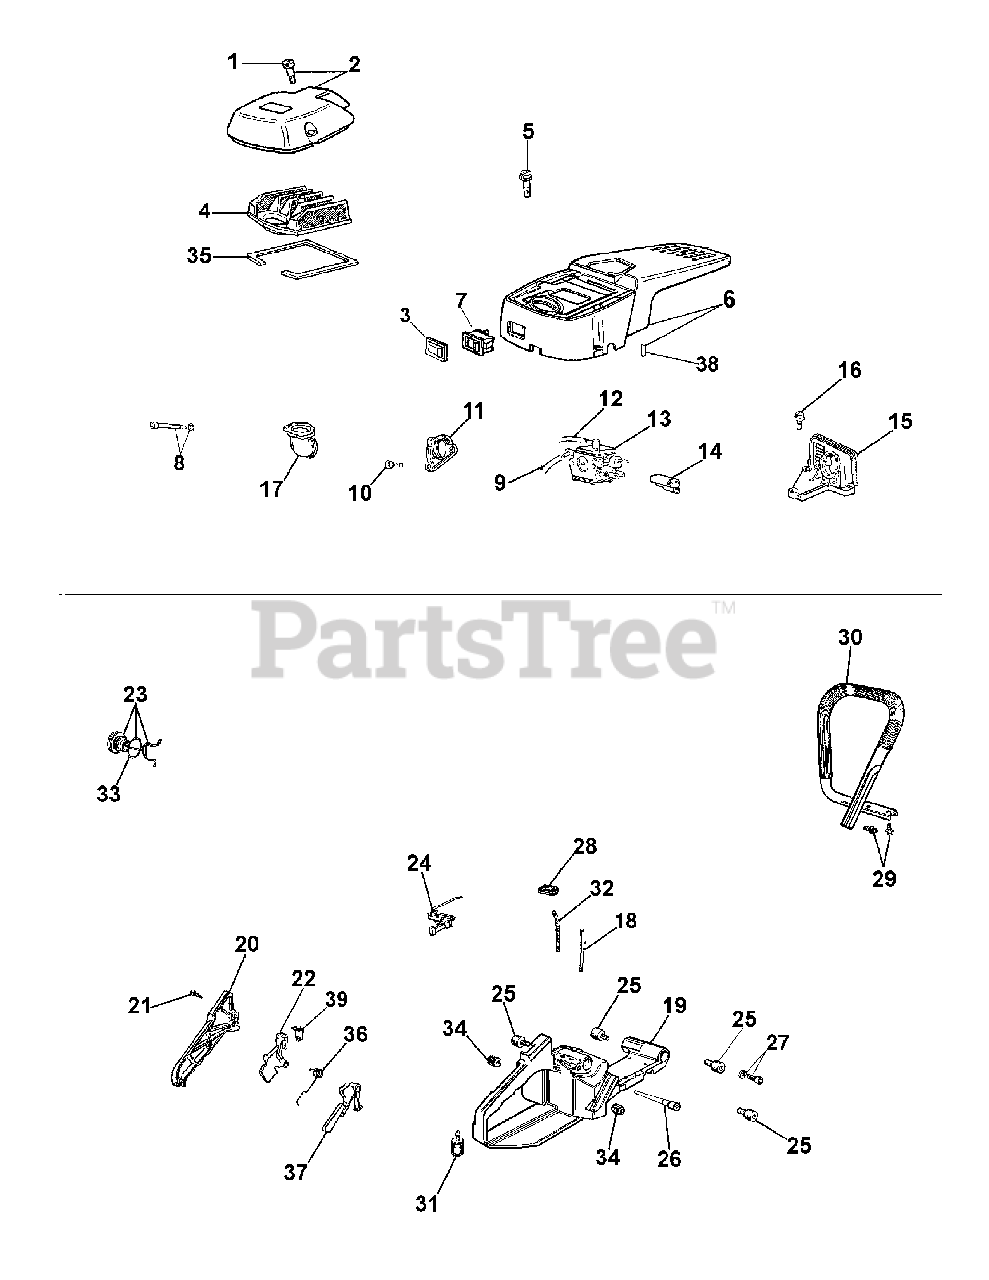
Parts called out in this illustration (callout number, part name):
2	AIR FILTER COVER
3	SWITCH GUARD.
6	CYLINDER COVER
7	SWITCH
13	CARBURETOR
14	SCREW GUIDE
16	SCREW
19	FUEL/OIL TANK
22	THROTTLE LEVER
24	THROTTLE LEVER
25	ANULAR BUFFER.
31	FUEL FILTER
34	ANULAR BUFFER
36	SPRING
